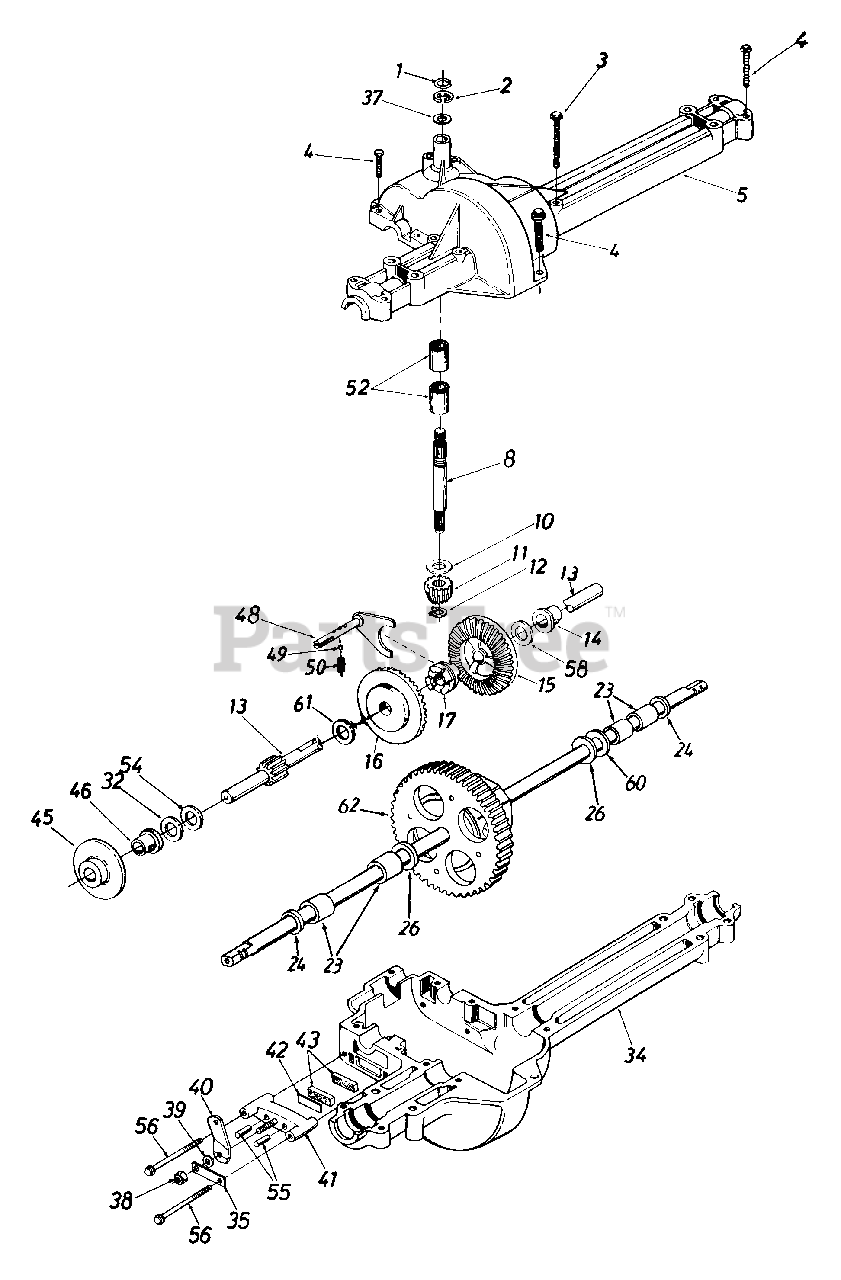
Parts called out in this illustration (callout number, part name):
1	Wire Ring
3	Hex Wash. TT-Tap 1/4-20 x 1.75" Lg.
4	Hex Tap Scr. 1/4-20 x 1.25" Lg.
5	Upper Housing
8	Input Shaft
10	Thrust Washer 5/8" I.D. x 1.25" O.D.
11	Pinion Input 14T
12	Retaining Ring
13	Drive Shaft - L.H. Brake
14	Flange Brg. 5/8" I.D. x 3/4" Lg.
15	Bevel Gear 42T - Small I.D.
16	Bevel Gear 42T - Large I.D.
17	Clutch Collar
23	Sleeve Bearing 3/4" I.D. x 1.0" Lg.
24	Oil Seal 3/4" I.D.
26	FI-Wash. .760" I.D. x 1.5" O.D.
32	Thrust Wash. 5/8" I.D. x 1" O.D. x .025" Thk.
32	Fi-Wash. 5/8" I.D. x 1" O.D. x .030" Thk.
32	Thrust Wash. 5/8" I.D. x 1" O.D. x .035" Thk.
32	Fl-Wash. 5/8" I.D. x 1" O.D. x .040" Thk.
34	Lower Housing
35	Anti-Rotation Brkt.
37	FI-Wash. 5/8" I.D. x 1" O.D. x .020" Thk.
37	Fl-Wash. 5/8" I.D. x 1" O.D. x .030" Thk.
37	Fl-Wash. 5/8" I.D. x 1" O.D. x .040" Thk.
38	Hex Nut 5/16-24 Thd.
39	FI-Wash. .344" I.D. x .875" O.D.
40	Actuating Arm
41	Brake Yoke
42	Puck Plate
43	Brake Puck
45	Brake Disc
46	Flange Bearing 5/8" I.D. x 15/16" Lg.
48	Shift Fork Ass'y.
49	Ball Detent .250" Dia.
50	Spring Detent
52	Needle Brg. 5/8" I.D. x 1/2" Lg.
54	Fl-Wash. 5/8" I.D. x 1" O.D. x .020 Thk.
55	Actuating Pin 5/16" Dia.
56	Hex Wash Hd. Self-Tap Scr. 1/4-20 Thd.
58	Fl-Wash. 5/8" I.D. x 1" O.D. x .020 Thk.
60	Fl-Wash. .76" I.D. x 1.5" O.D. x .010" Thk.
60	Fl-Wash. .76" I.D. x 1.5" O.D. x .020" Thk.
60	Fl-Wash. .76" I.D. x 1.5" O.D. x .030" Thk.
60	Fl-Wash. .76" I.D. x 1.5" O.D. x .060" Thk.
61	Thrust Washer
62	Differential Ass'y.
